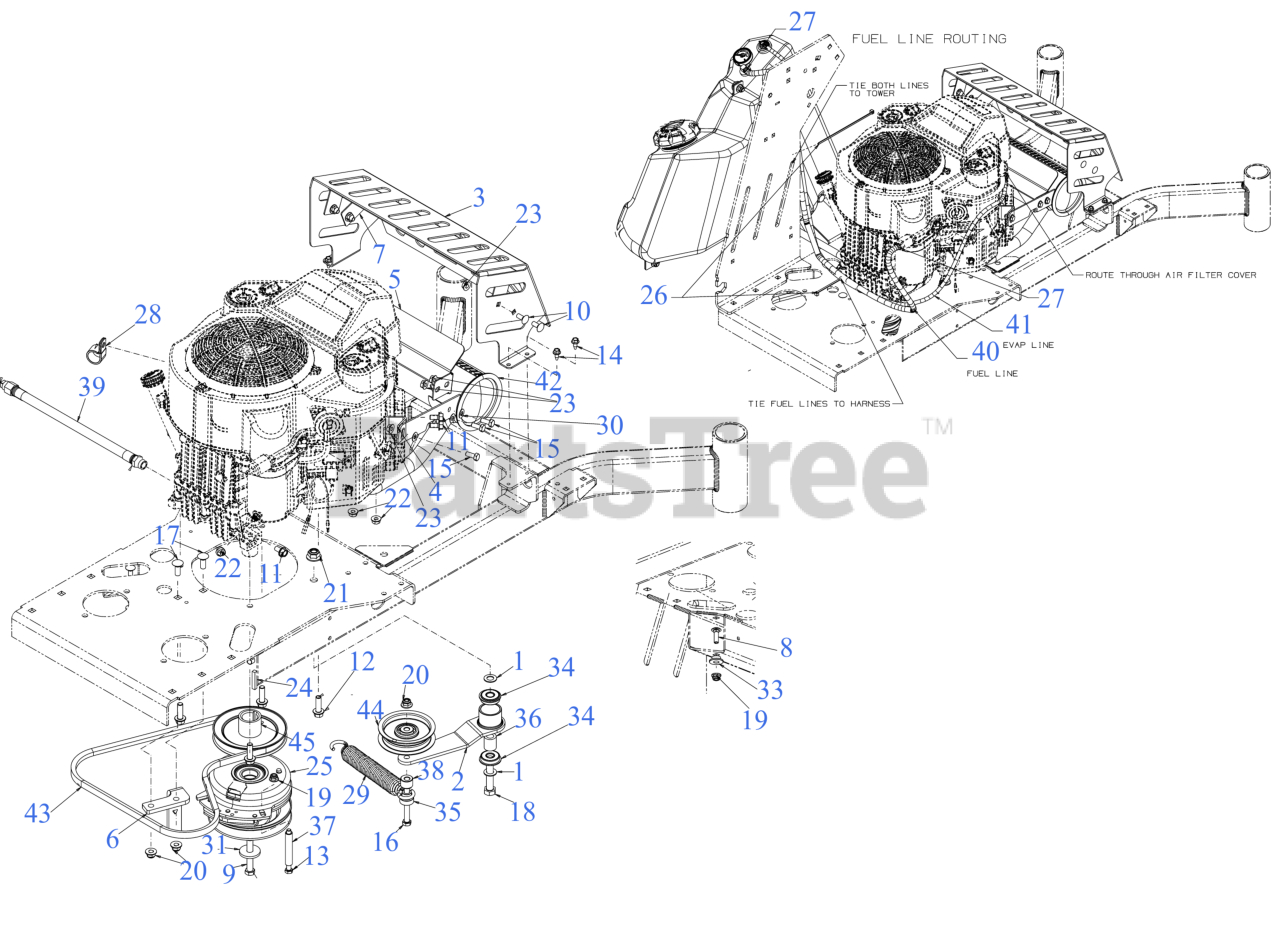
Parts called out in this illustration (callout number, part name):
1	THRUST WASHER
2	IDLER BRACKET ASSEMBLY
3	MUFFLER SHIELD
4	MUFFLER MOUNTING BRACKET
5	MUFFLER SHIELD
6	CLUTCH BRACKET
7	MUFFLER SHEILD BRACKET
8	CARRIAGE BOLT 5/16-18 x 1.00
9	SCREW 7/16-20:2.75 GR5
10	CARRIAGE BOLT 5/16-18 x .75
11	SCREW M8 x 1.25 x 16MM GR8.8
12	SCREW 3/8-16 x 1.25 GR5
13	SCREW 5/16-18X3.5 GR5
14	SCREW 1/4-20X.625
15	SCREW 5/16-18 x .75 GR5
16	SCREW 3/8-16 x 3.25 GR8
17	CARRIAGE BOLT 3/8-16 x 1.00 GR5
18	SCREW 1/2-13 x 2.75 GR5
19	FLANGE LOCK NUT 5/16-18
22	HEX FLANGE NUT
23	HEX FLANGE NUT
24	SQUARE KEY 1/4 x 1.50
25	PTO CLUTCH
26	7" CABLE TIE
27	HOSE CLAMP 1/20
28	HOSE CLAMP 1.0"
29	SPRING 1.25" DIA x 8.5" LONG
30	FLAT WASHER
31	FLAT WASHER .45 x 1.5 x .172 HT
33	SHOULDER SPACER
34	ROLLER BEARING .5X1.37X.44
35	SHOULDER SPACER
36	SPACER 0.51 x 0.88 x 1.00
37	SPACER .5 x .334 x 2.75
38	SPACER .38 x .895 x .61
39	OIL DRAIN HOSE
40	FUEL HOSE LOW PERMEATION 36"
41	VENT HOSE 3/16 ID 65"LG
42	MUFFLER (ROUND)
43	V-BELT A SEC x 48"
44	FLAT IDLER PULLEY 3.5
45	PUMP DRIVE PULLEY 5.33 DIA
